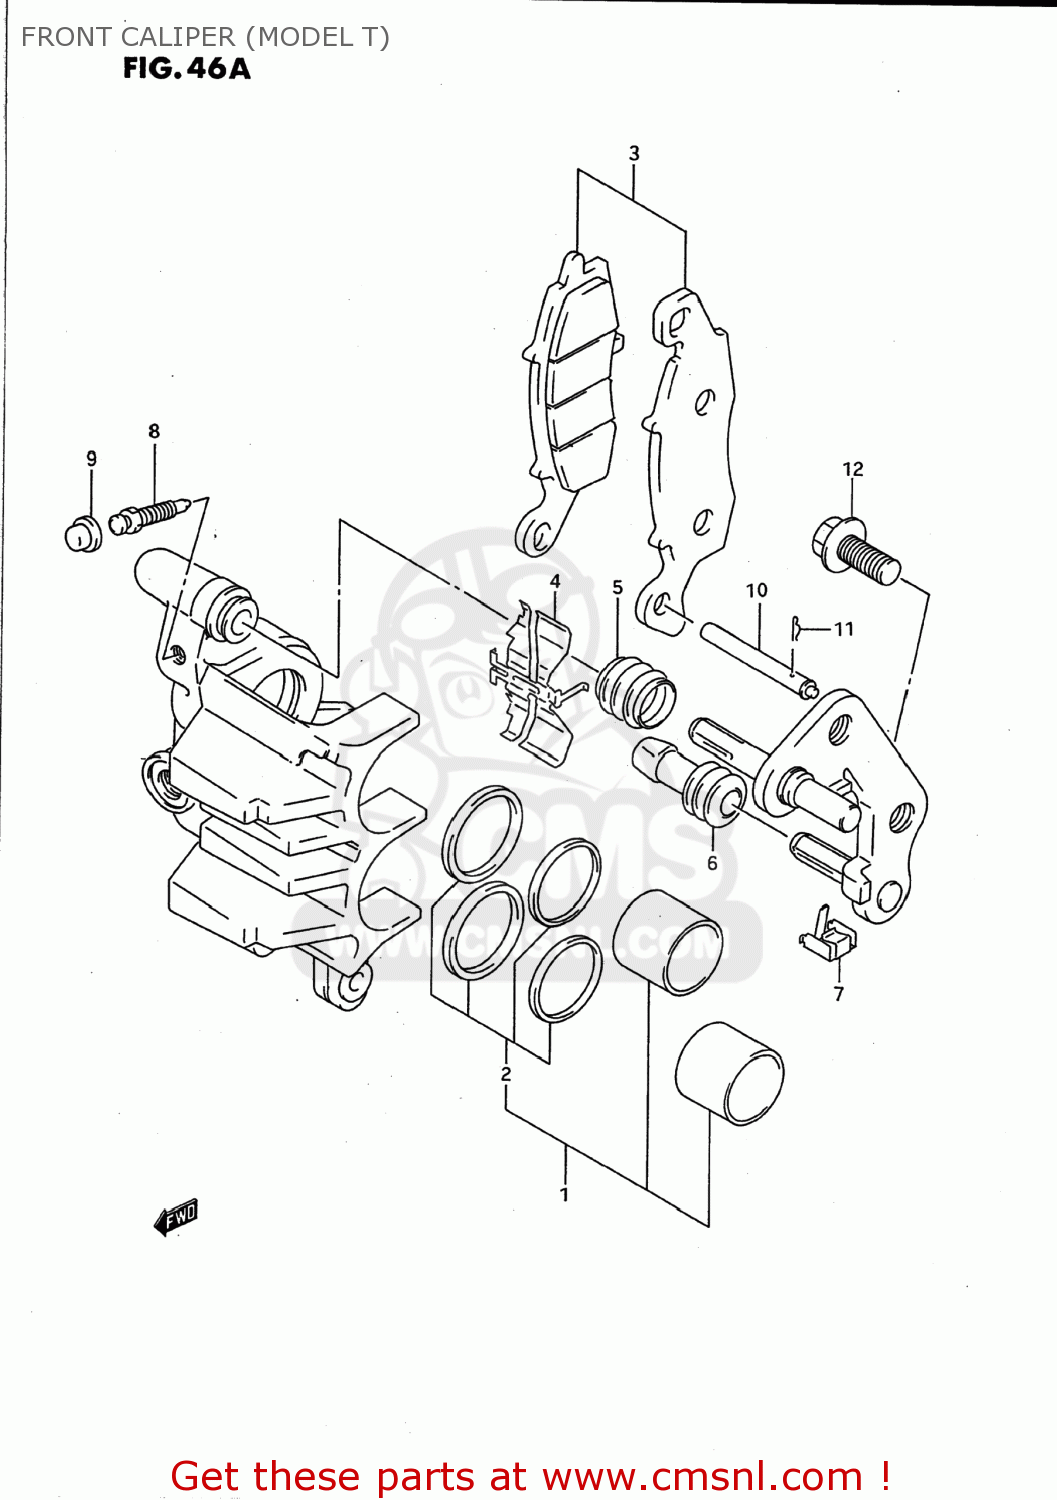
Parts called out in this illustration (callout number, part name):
1	PISTON SET
2	SEAL SET,PISTON
3	PAD SET (NAS)
4	SPRING,PAD,R
5	BOOT,AXLE
6	INSULATOR,AXLE
7	GUIDE,PAD
8	BLEEDER
9	CAP,BLEEDER PLUG
10	PIN,PAD
11	CLIP,PAD PIN
12	BOLT
